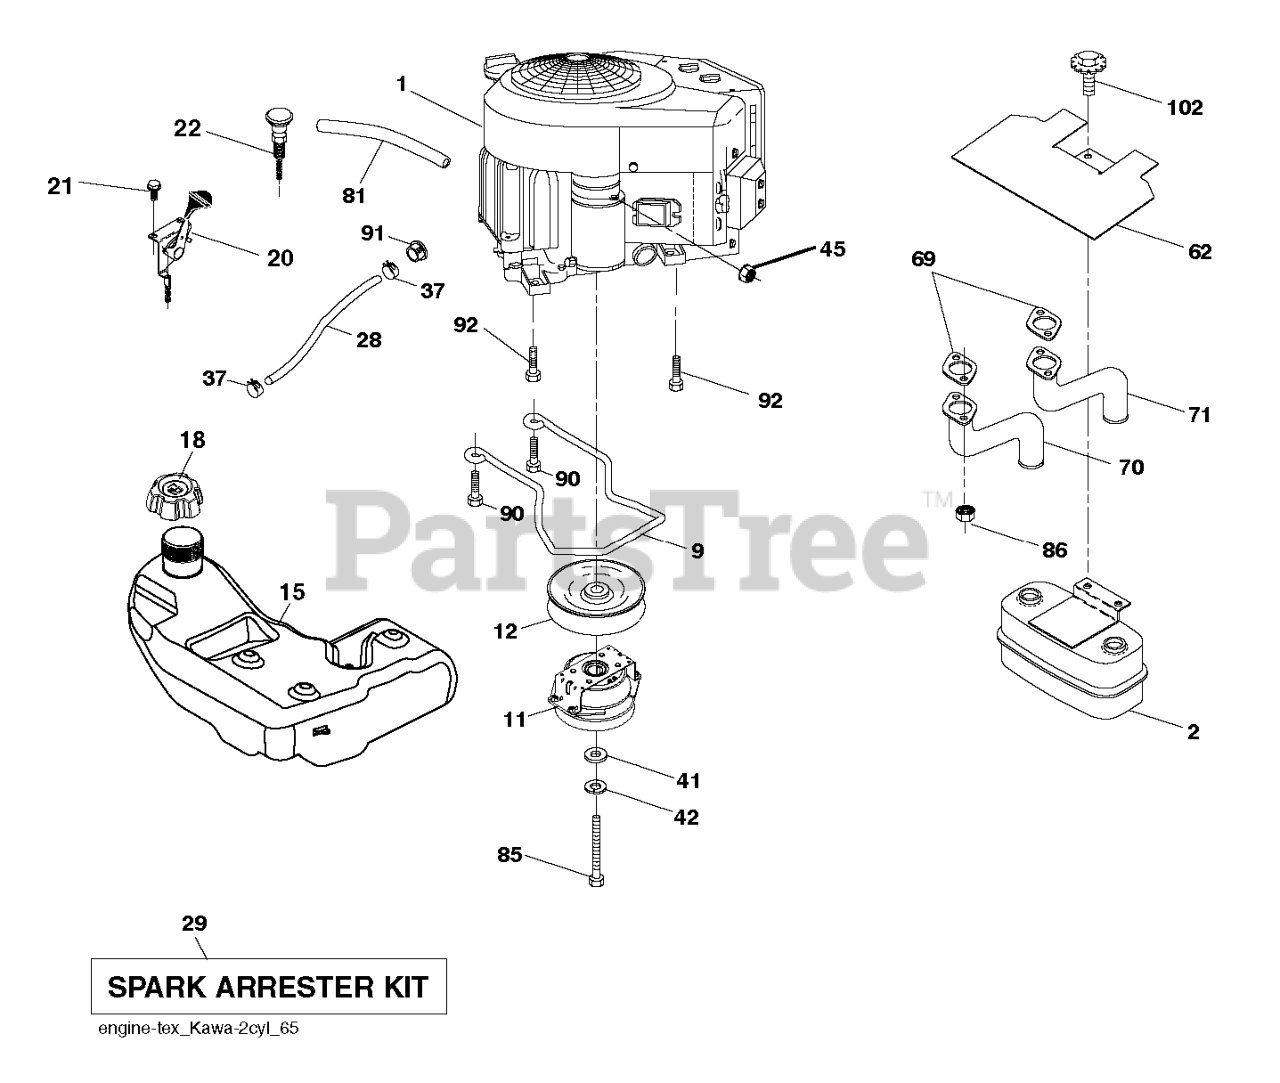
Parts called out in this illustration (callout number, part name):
2	MUFFLER.ASM.TWIN.MNTG.BRACKET
9	KEEPER.BELT.ENG.4.25"2.BLT.431
11	CLUTCH.OGURA.5.0PD.GT1.5A-EH07
12	PULLEY.ENGINE.TUFFTORQ
15	Tanks
18	FUEL CAP
18	CAP ASSY FUEL 3" GRAY
20	CONTROL.THROTTLE.COBRA.BLACK
22	CONTROL, CHOKE
28	HOSE.1/4".LOW.PERM.FUEL.LN.60"
29	KIT.SPARK ARRESTOR 794945 B&S
37	HOSE CLAMP
62	SHIELD.HEAT.MUFFLER
70	TUBE.EXHAUST.LH.FR961/FR730
71	TUBE.EXHAUST.RH.FR961/FR730
81	TUBE, DRAIN OIL ASM.
85	BOLT.HEX.7/16-20X3.75.GR5.RED
86	NUT.HEX.FLANGE.TOPLOCK
90	SCREW 3/8-16X1
91	BUSHING.1.375OD
92	SCREW 3/8-16X1
102	SCREW
